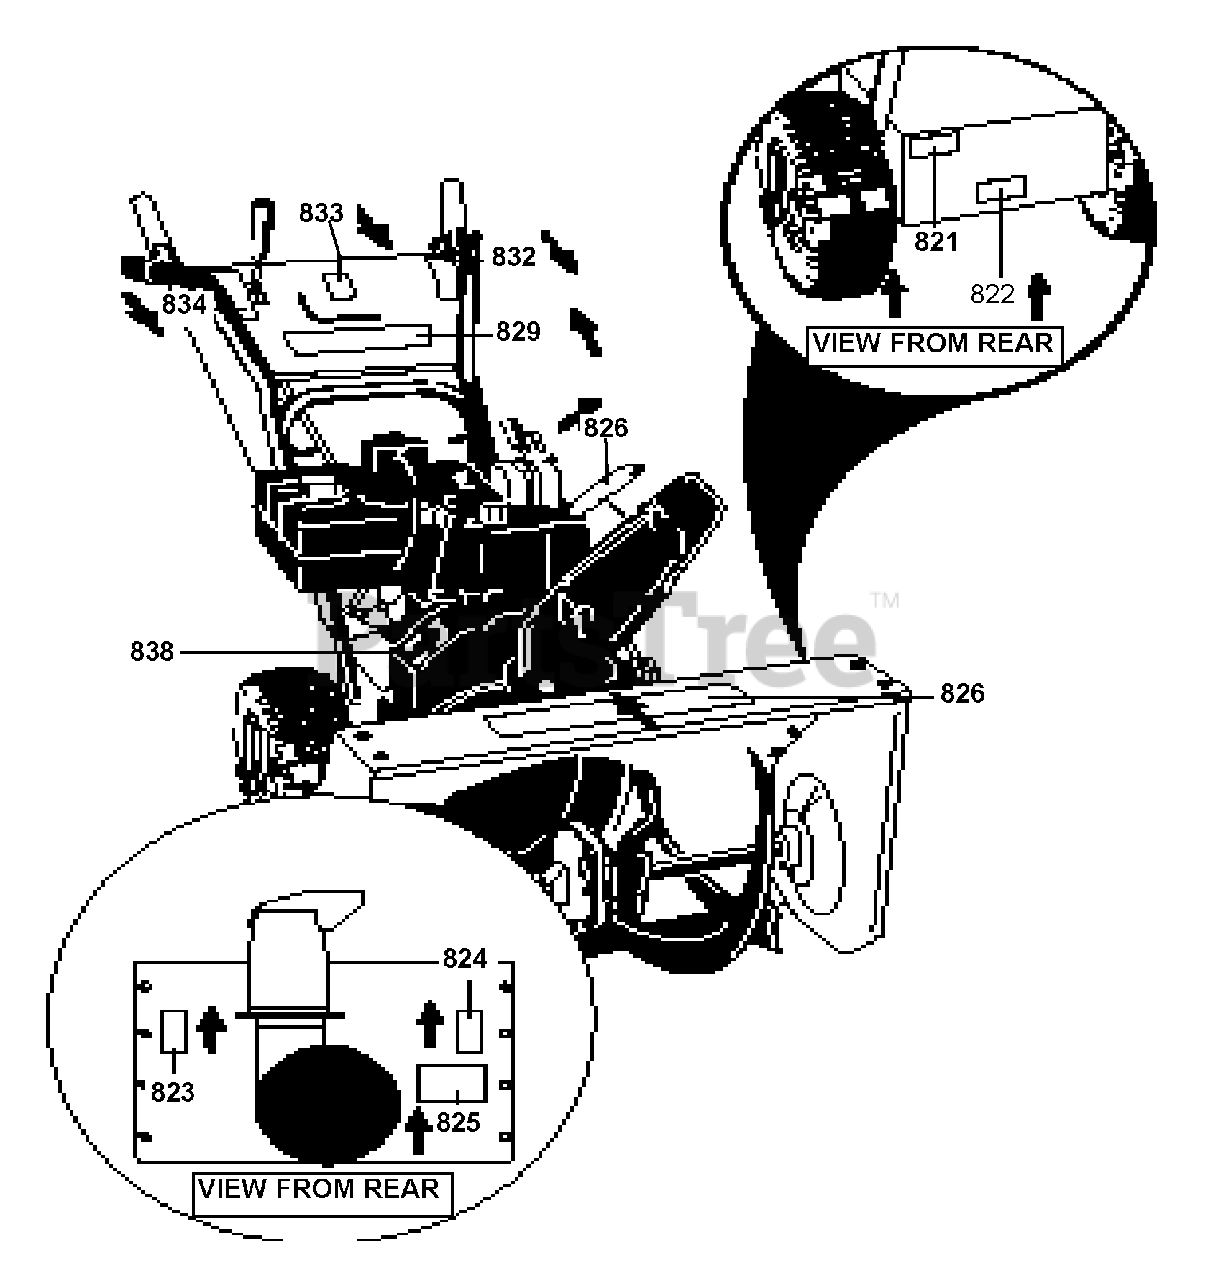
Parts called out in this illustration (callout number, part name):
821	NOT A SEVICABLE PART
822	DECAL, OVER ADJ OF DISC
823	DECAL, DANGER CHUTE
824	DECAL, DANGER AUGER
825	DECAL, DANGER
826	DECAL, ST824E
829	DECAL, CROWN
832	DECAL, TRACTION DRIVE
833	DECAL, SNOW CONDITIONS
834	DECAL, GEAR SELECT
835	DECAL, CONTROL PANEL
838	DECAL, BELT STRETCH & ADJ
